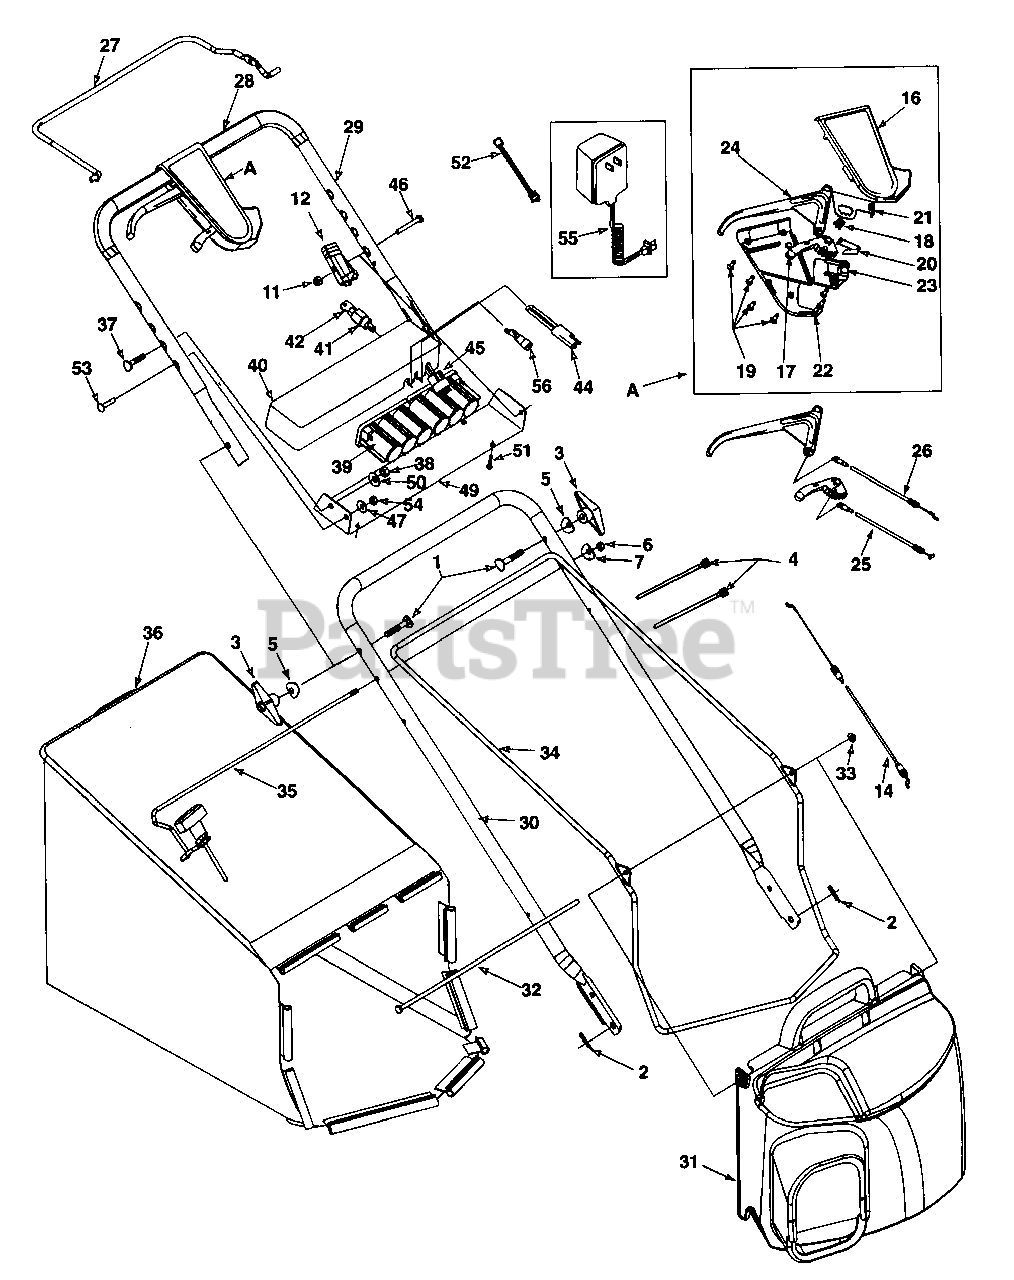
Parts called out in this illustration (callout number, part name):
1	Bolt Cur. Carr. 5/16-18 x 2.0
2	Cotter Pin .072 x 1.12 Lg.
3	Knob Assembly 5/16-18
4	Strap 4.3" Lg.
5	Wash. Sad. .320 ID x .830 OD
6	Handle Knob 1/4-20
7	Saddle Washer
11	Nut 1/4-20 Top Lock Nut Insert
12	Control Cable Housing
14	Control Cable 44" Lg.
16	Upper Control Housing
17	6-Speed Shift Lever
18	Gear Insert
19	C Sunk Tap Screw #10-16 x .625
20	Shift Lever Spring
21	6 Spd. Rack Cable Brkt.
22	Lower Control Housing
23	Cable Mounting Cap
24	Control Lever
25	6 Spd. Cable
26	Self Prop. Cable, 52"
28	Foam Grip
31	Grassbag Cover w/logo
32	Pivot Rod
33	Cap Nut
36	Grassbag
37	Cur. Carr. Bolt 5/16-18 x 1" Lg.
38	Hex Nut 5/16-18 Thd.
39	Battery Pack - 12 Volt
40	Battery Tray
41	Ignition Switch
42	Ignition Key
44	Plug
45	Wire Harness
46	Hex Bolt 1/4-20 x 1.3" Lg.
47	Bell Wash 1/4" I.D.
51	Truss Mch. Tap Scr. 1"
52	Harness Ext.
53	Scr. 1/4-20 x 1.25
54	Hex Nut 1/4-20
55	Battery Charger
56	Fuse Holder
